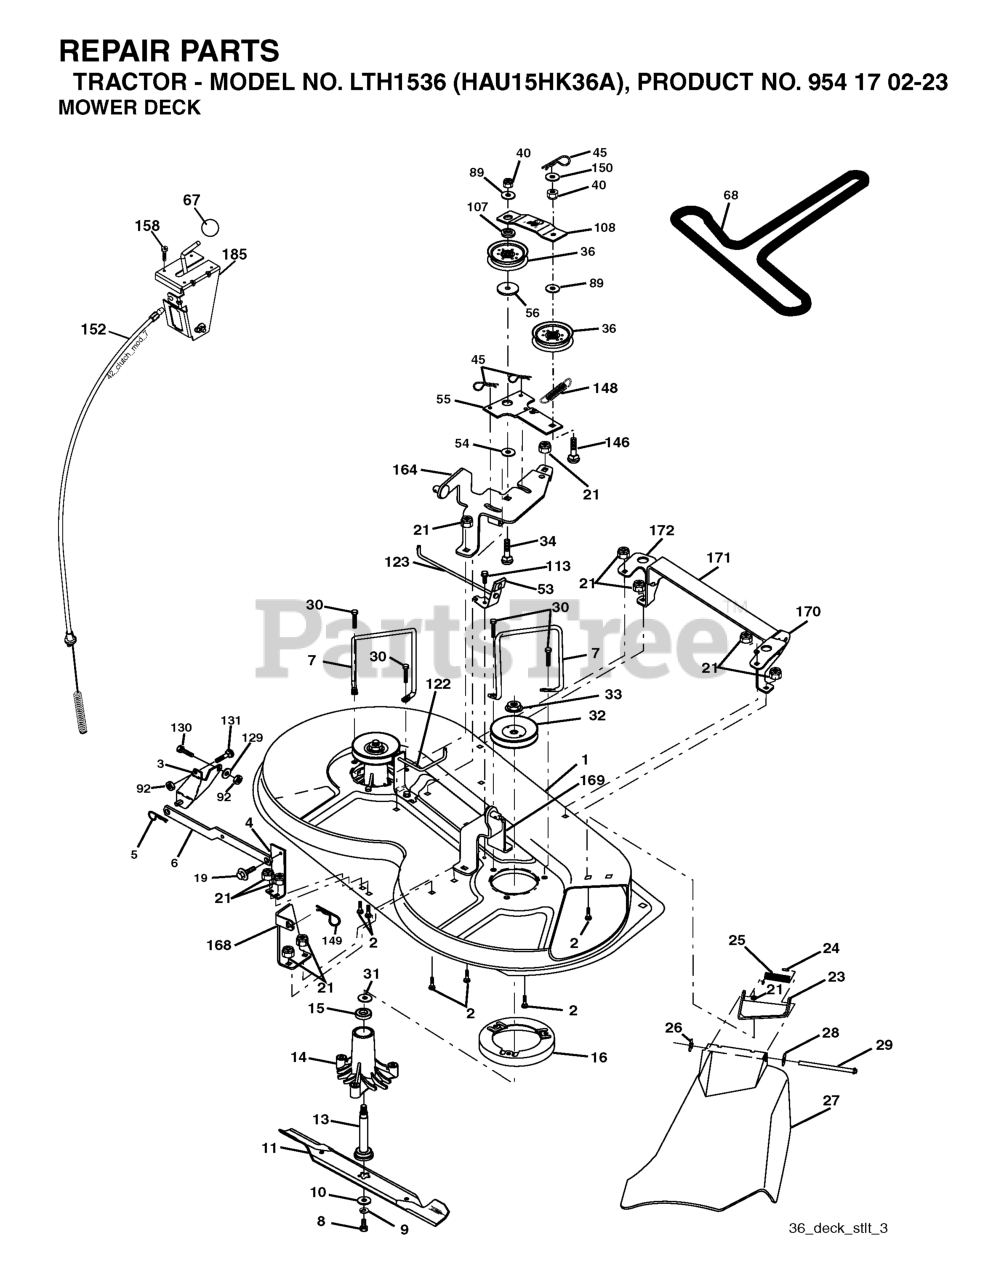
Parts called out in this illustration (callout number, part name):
2	RP BOLT 5/16-18 X3/4 ZN/YEL GR
3	BRKT ASM SWAY BAR
5	RETAINER-SPRNG RB
6	BAR SWAY DECK
8	BLADE BOLT
9	LOCKWASHER
10	WASHER.BLADE
11	BLADE, HI-LIFT 36" PREMIUM
13	SHAFT ASM VENT
14	HOUSING.MANDREL.VENTED (MACHD)
16	STRIPPER.MANDREL.ROUND.BLACK
19	BOLT SHD 5/16-18
21	LOCKNUT
23	BRACKET ASM DEFLECTOR
24	CAP-SLEEVE LT
25	SPRING TORSION
26	NUT PUSH M
27	CONSOLE.STLT.5SP.BLK
28	Washer 11/32 x 5/8 x 16 Ga SD
29	HINGE ROD
30	SCREW, WASHER HEAD
31	WASHER.SPACER.MANDREL
32	PULLEY, MANDREL
33	NUT, FLG TOPLOCK 9/16"
36	FLAT IDLER PULLEY
45	RETAINER M
53	BRAKE ASSEMBLY
56	SPACER.RETAINER.MOWER
67	KNOB T (3/8 HOLE)
89	WASHER
92	NUT
107	SPACER.IDLER.ARM
108	STIFFENER.IDLER.ARM
113	Screw 5/16-18 x 1/2 Hex, Self Tapping 5/16-18 x 1/2
129	WASHER
131	BOLT D
146	BOLT, CARRIAGE IDLER
148	IDLER RETURN SPRING
149	SPRING.RETAINER.YELLOW.ZINC
158	SCREW
171	BRACE.SUPT.SUSP.FRT.CRD
185	HEAD ASM. CABLE CLUTCH
